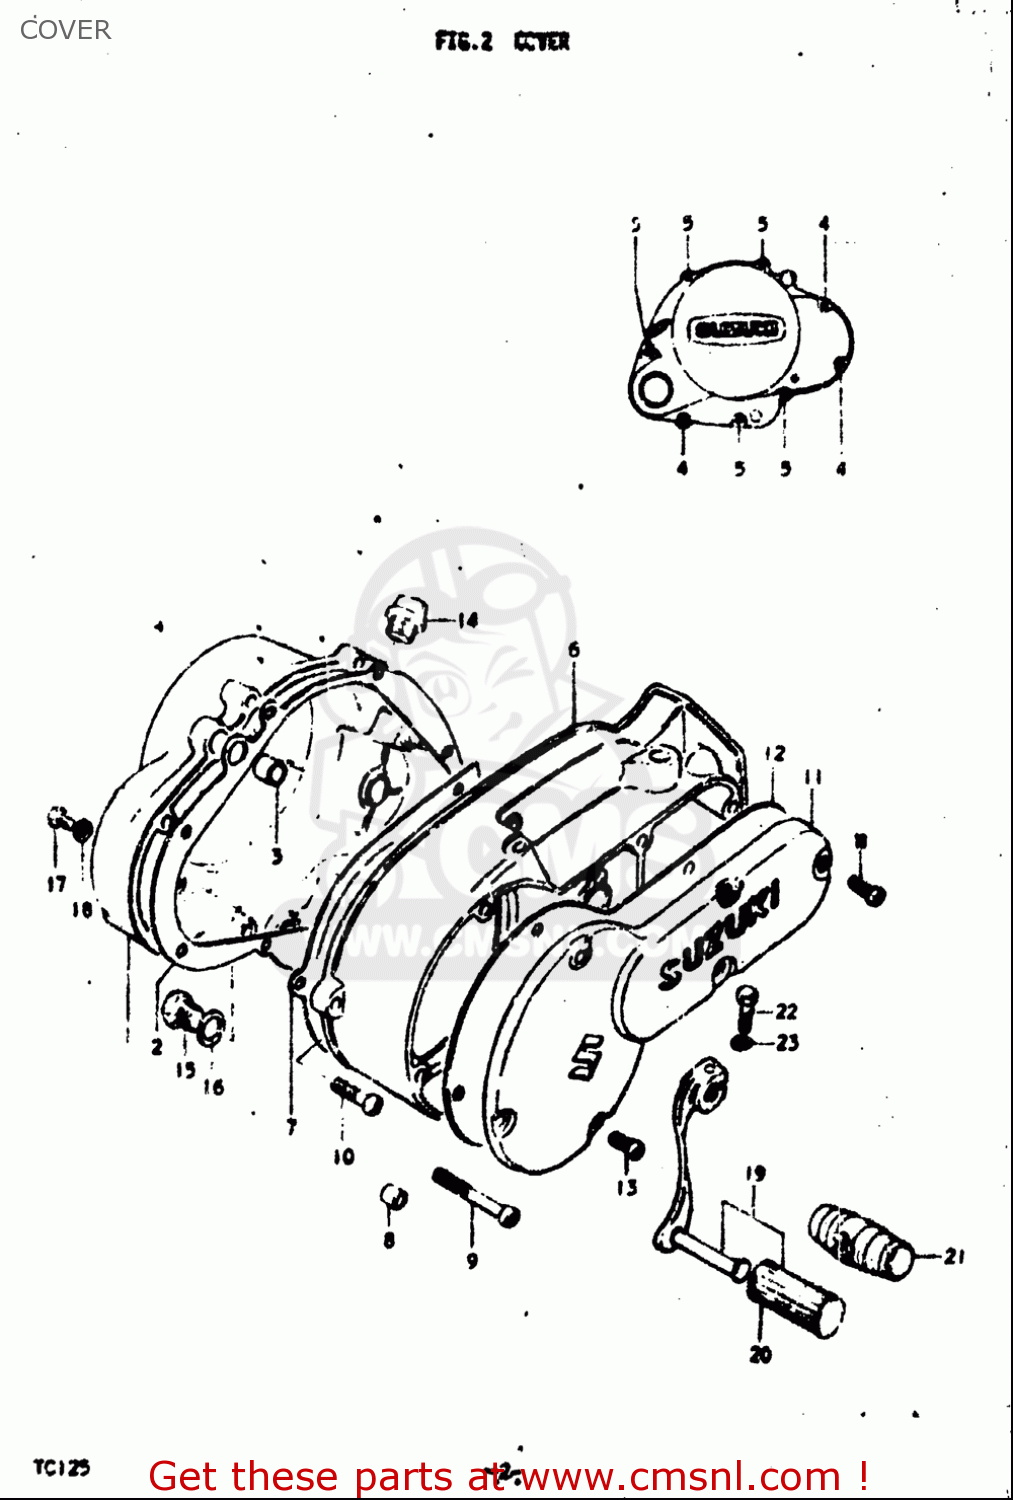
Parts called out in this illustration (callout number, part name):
2	GASKET,CLUTCH COVER (NAS)
3	PIN
4	SCREW
5	SCREW
9	SCREW
10	SCREW
13	SCREW
14	PLUG
15	PLUG(MAGNETO)
16	GASKET(14X19.2X2) (NAS)
18	GASKET(6.2X11X1) (NAS)
19	LEVER ASSY,GEAR SHIFT
20	RUBBER,GEAR SHIFT PEDAL
21	RUBBER,GEAR SHIFT PEDAL
22	BOLT
23	WASHER,LOCK
